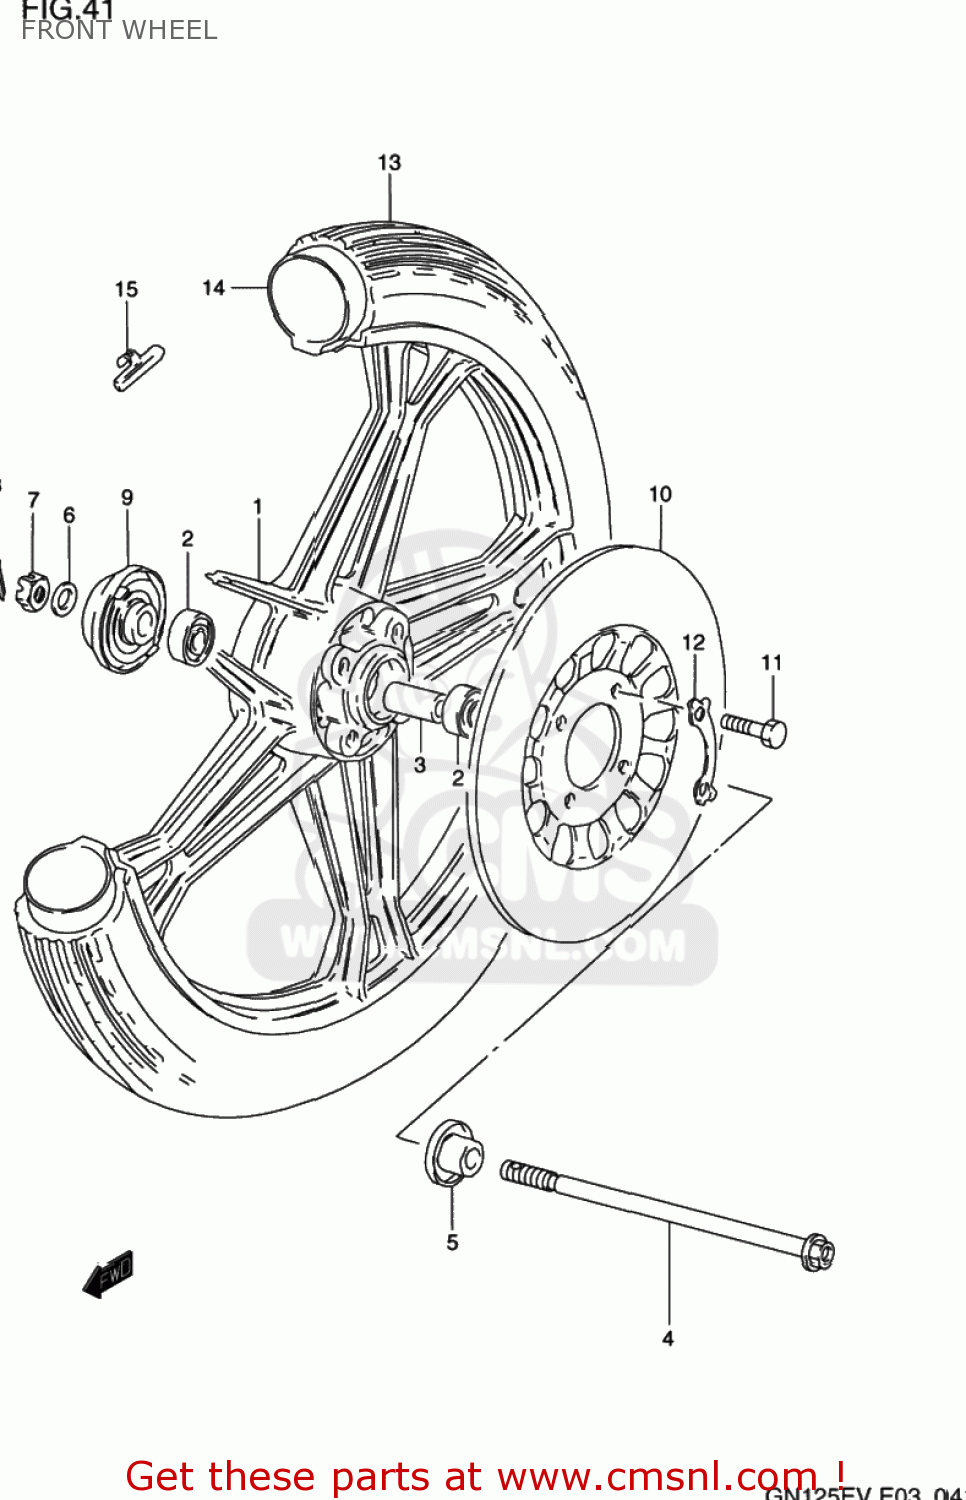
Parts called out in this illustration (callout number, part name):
1	WHEEL,FR(1.60X18)
2	BEARING
3	SPACER(12.5X19X52)
4	AXLE,FR
5	SPACER,FR AXLE,L
6	WASHER
7	NUT
8	COTTER PIN
9	BOX ASSY,SPEEDOMETER GEAR
10	DISC,FR BRAKE
11	BOLT(8X25)
12	WASHER
13	TIRE,FR(2.75-18)
14	TUBE,INNER
15	BALANCER,WHEEL NO.3.10
